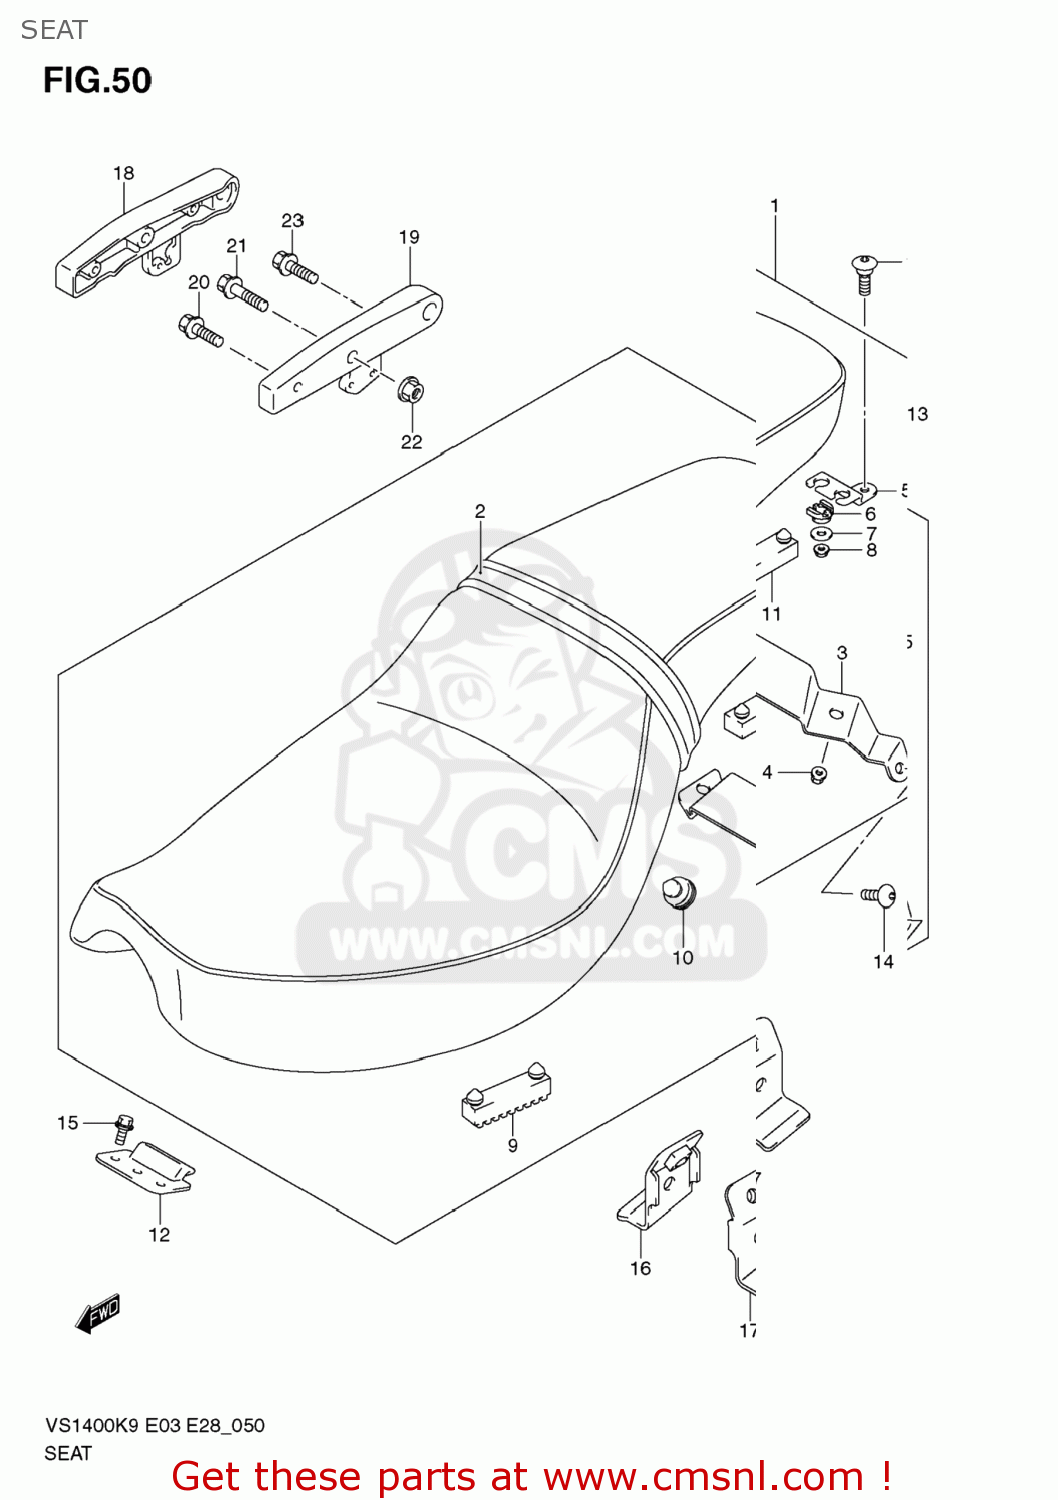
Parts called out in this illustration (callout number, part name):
1	SEAT ASSY
2	BAND ASSY
3	BRACKET,BAND
4	NUT
5	BRACKET,SEAT RR
6	CUSHION
7	WASHER(6.5X20X1.6)
8	NUT
9	CUSHION,SEAT
10	CUSHION,FR
11	CUSHION,SEAT
12	BRACKET,SEAT FR
13	SCREW(6X16)
14	BOLT(6X12)
15	BOLT
16	BRACKET,SEAT CTR,R
17	BRACKET,SEAT CTR,L
18	HANDLE,PILLION RIDER,R
19	HANDLE,PILLION RIDER,L
20	BOLT
21	BOLT
22	NUT
23	BOLT
